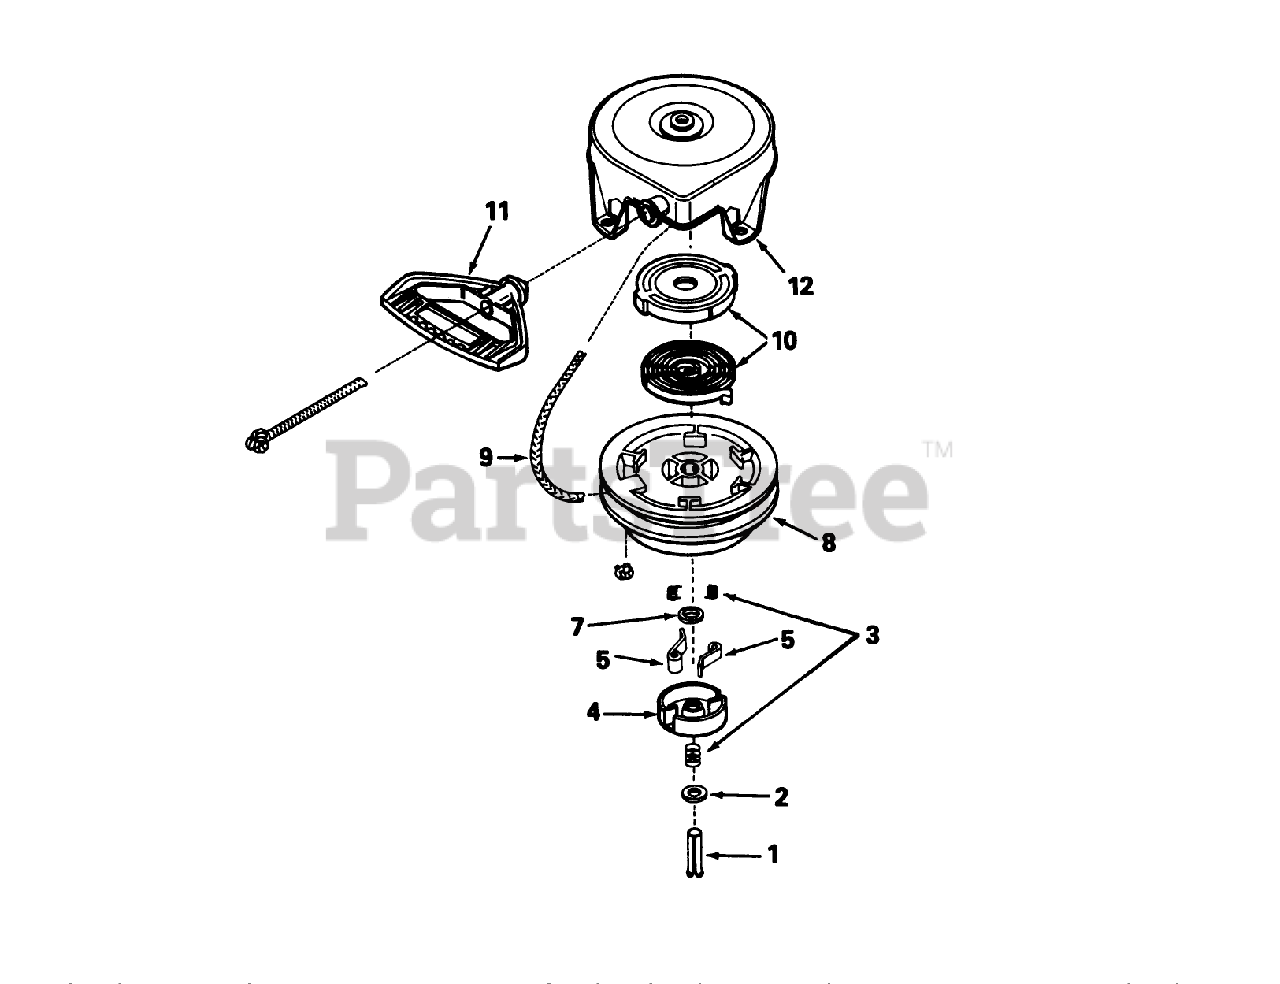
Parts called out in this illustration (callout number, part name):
1	Pin, Spring (Incl. Ref. #7)
2	Washer
3	Spring Assembly
4	Retainer
5	Dog-Starter
7	Washer
8	Pulley
9	Rope-Starter
10	Spring Keeper Assy.
11	Handle-Starter, Mitten Grip
12	Housing Assy., Starter
